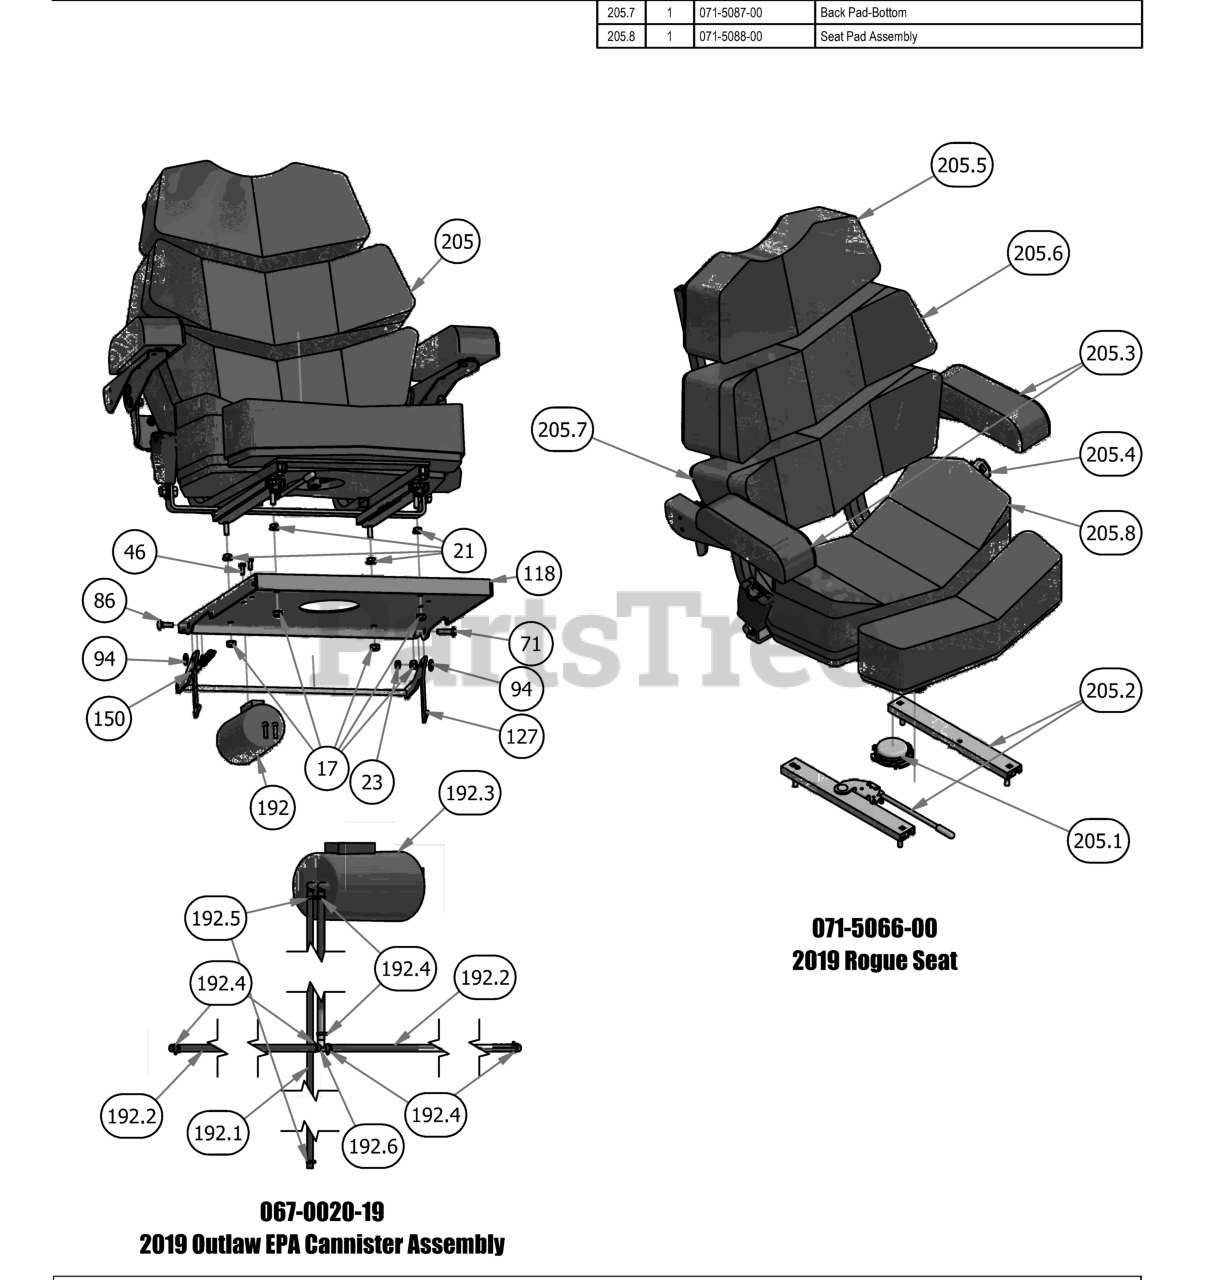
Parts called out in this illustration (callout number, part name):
17	5/16-18 Nylon Flange Nut
21	5/16" Flange Nut
23	5/16-18 Nylock Jam Nut 1/2 Nut
46	M6-1.0 X 16MM Hex Bolt
71	5/16" x 1 1/4" Carriage Bolt
86	5/16" x 1" Carriage Bolt
94	.360 ID Plastic Washer
118	2019 Outlaw Seat Plate
127	Seat Latch Rod Assembly
150	Brake Spring
192	2019 Outlaw EPA Cannister Assembly
192.1	3/16" Vinyl Tubing, 66" Long
192.2	1/4" Vinyl Tubing 38" Long
192.3	Carbon Canister
192.4	3/16 Vinyl Clamp
192.5	3/16" Vinyl Hose Clamp
192.6	fuel line T
205	2019 Rogue Seat
205.1	Seat Switch
205.2	Seat Rails
205.3	Arm Rest Kit
205.4	Seat Belt
205.5	Back Pad-Top
205.6	Back Pad-Middle
205.7	Back Pad-Bottom
205.8	Seat Pad Assembly
